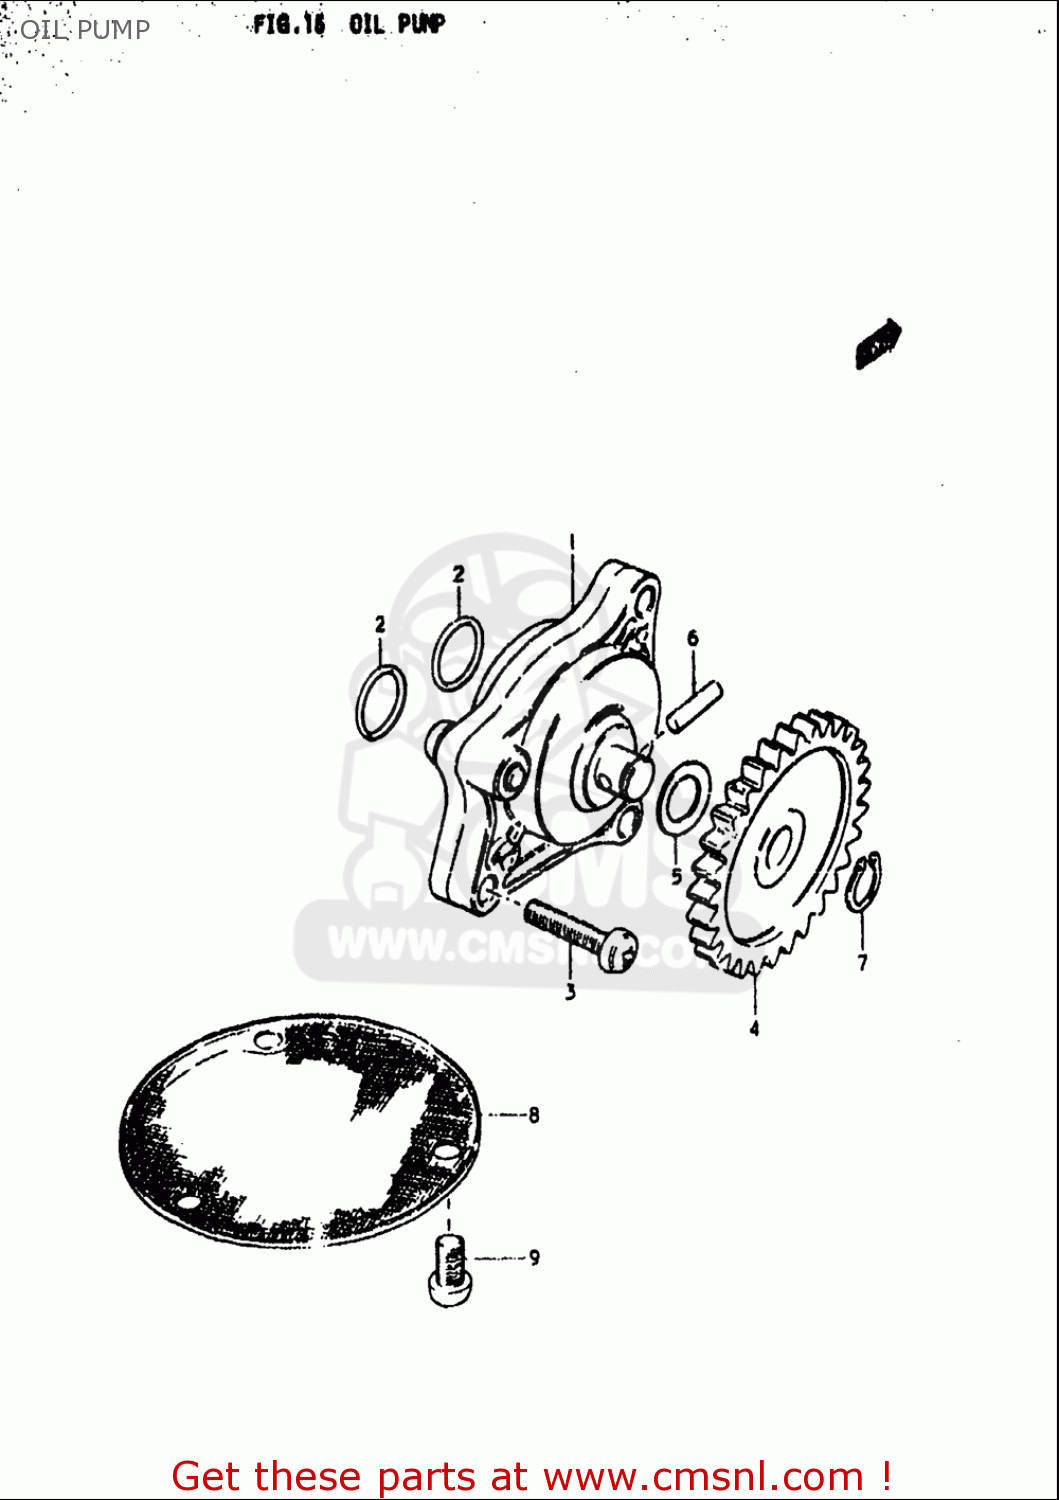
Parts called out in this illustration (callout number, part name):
1	PUMP ASSEMBLY,ENGINE OIL
2	O RING(D:1.9,ID:13)
3	SCREW
4	GEAR,ENG OIL PUMP DRIVEN(NT:33
5	SHIM
6	PIN(4X15.8)
7	CIRCLIP
8	STRAINER,ENGINE OIL
9	SCREW
